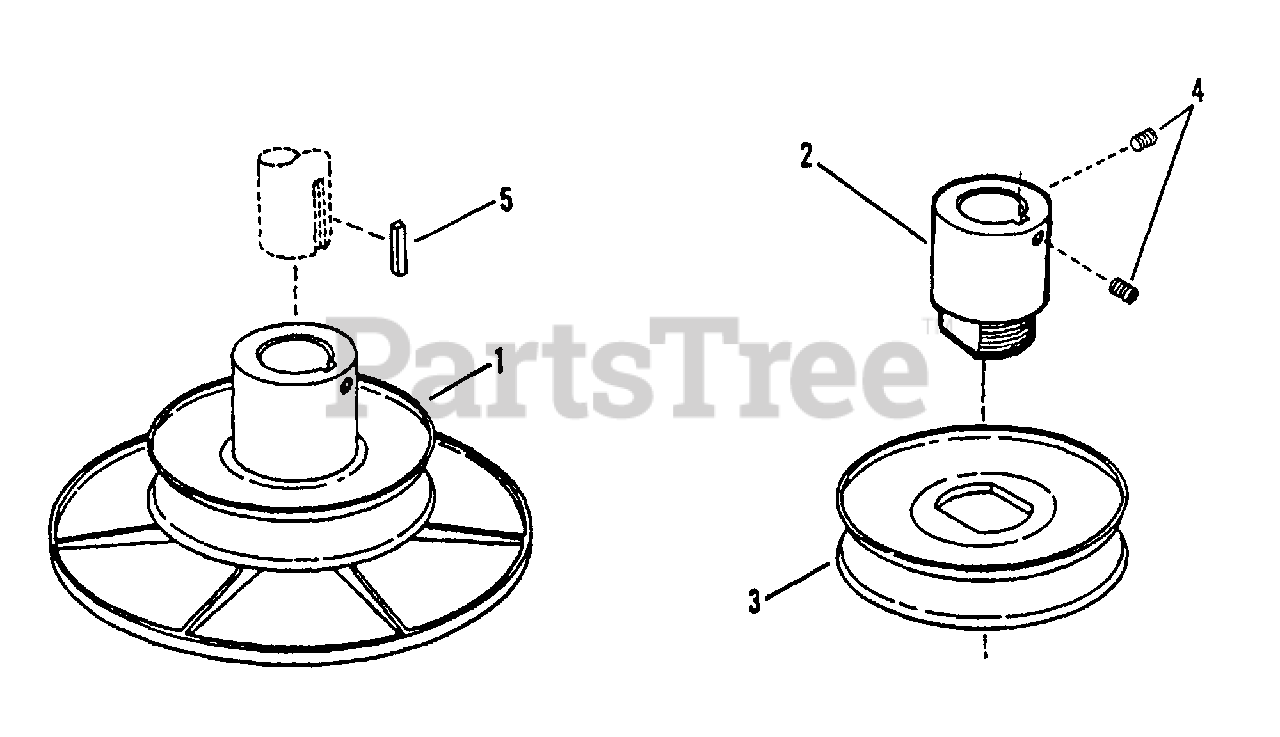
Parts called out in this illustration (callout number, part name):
1	ASSEMBLY, 5.18" O.D. Drive Disc
1	ASSEMBLY, 6" O.D. Drive Disc
3	PULLEY, Drive (6.0" O.D.)
3	PULLEY, Drive (5.18" O.D.)
4	SET SCREW, 3/8-16 x 3/8"
5	KEY, 1/4" Square x 2"
